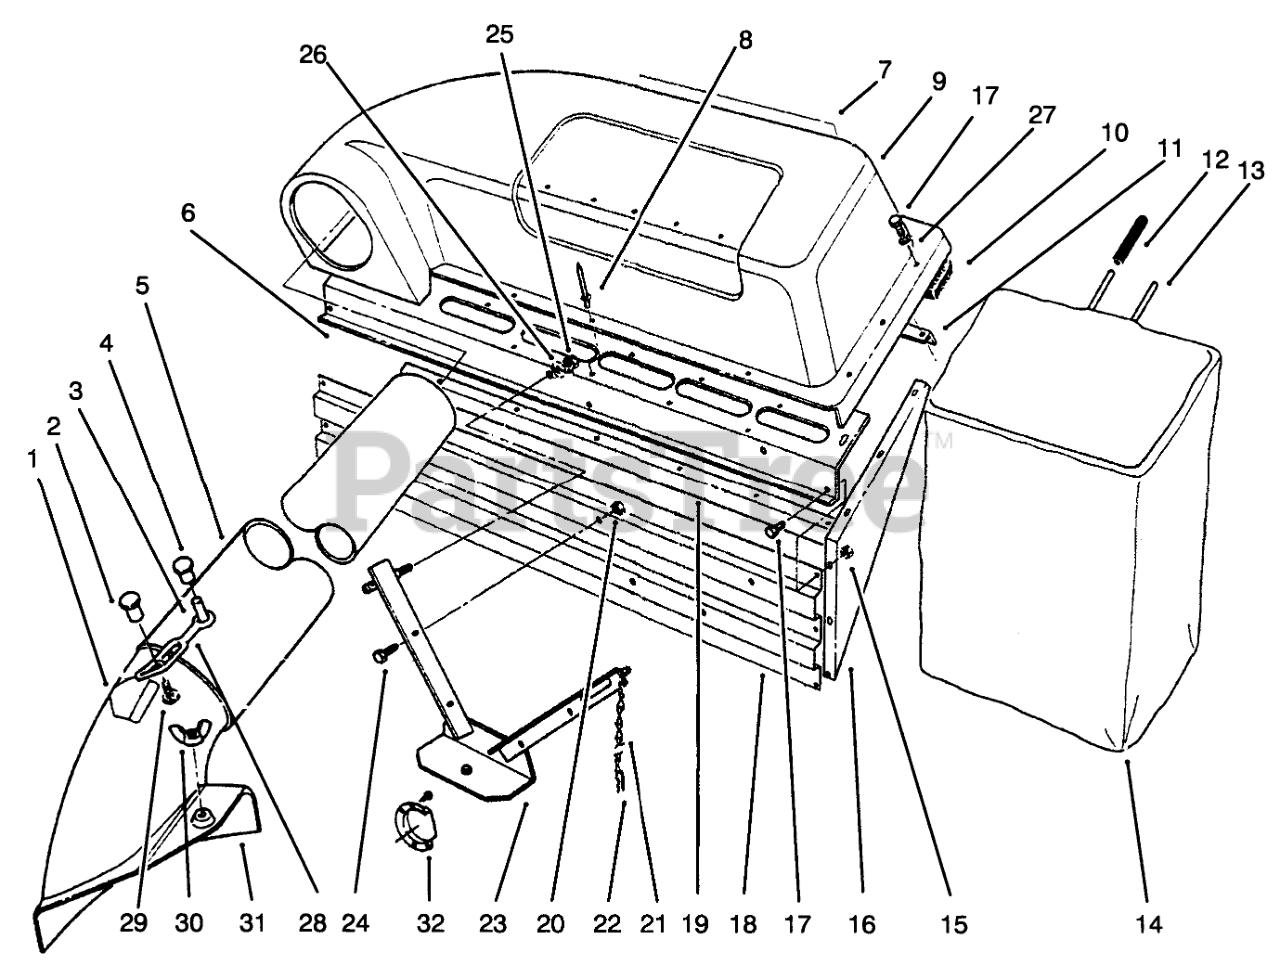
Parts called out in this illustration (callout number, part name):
1	DECAL-DANGER
3	SPACER-INTERLOCK
4	FASTENER-PANEL
6	COVER SUPT BAFFLE B
7	Decal-Twin Bagger
8	RIVET-POP
9	COVER
10	FOAM SEAL
11	BAG FRAME BRKT
12	GRIP-HANDLE, BAG
13	BAG FRAME
15	NUT-LOCK, NI
16	Plate-Side
17	SCREW-HH
18	MUFFLER SHIELD
19	BAG SUPPORT CHANNEL
20	NUT-LOCK, NI
21	6-LINK CHAIN W/HOOK
22	PIN-HAIR
23	V-Bracket
24	SCREW-HH
25	NUT-LOCK, NI
26	WASHER-FLAT
27	WASHER-FLAT
28	RETAINER-DUCT
29	SCREW-HWH
30	NUT-WING SPECL
31	Assembly-Chute (Incl. Ref. #1, 2 & 29)
32	MUFFLER DEFLECTOR
